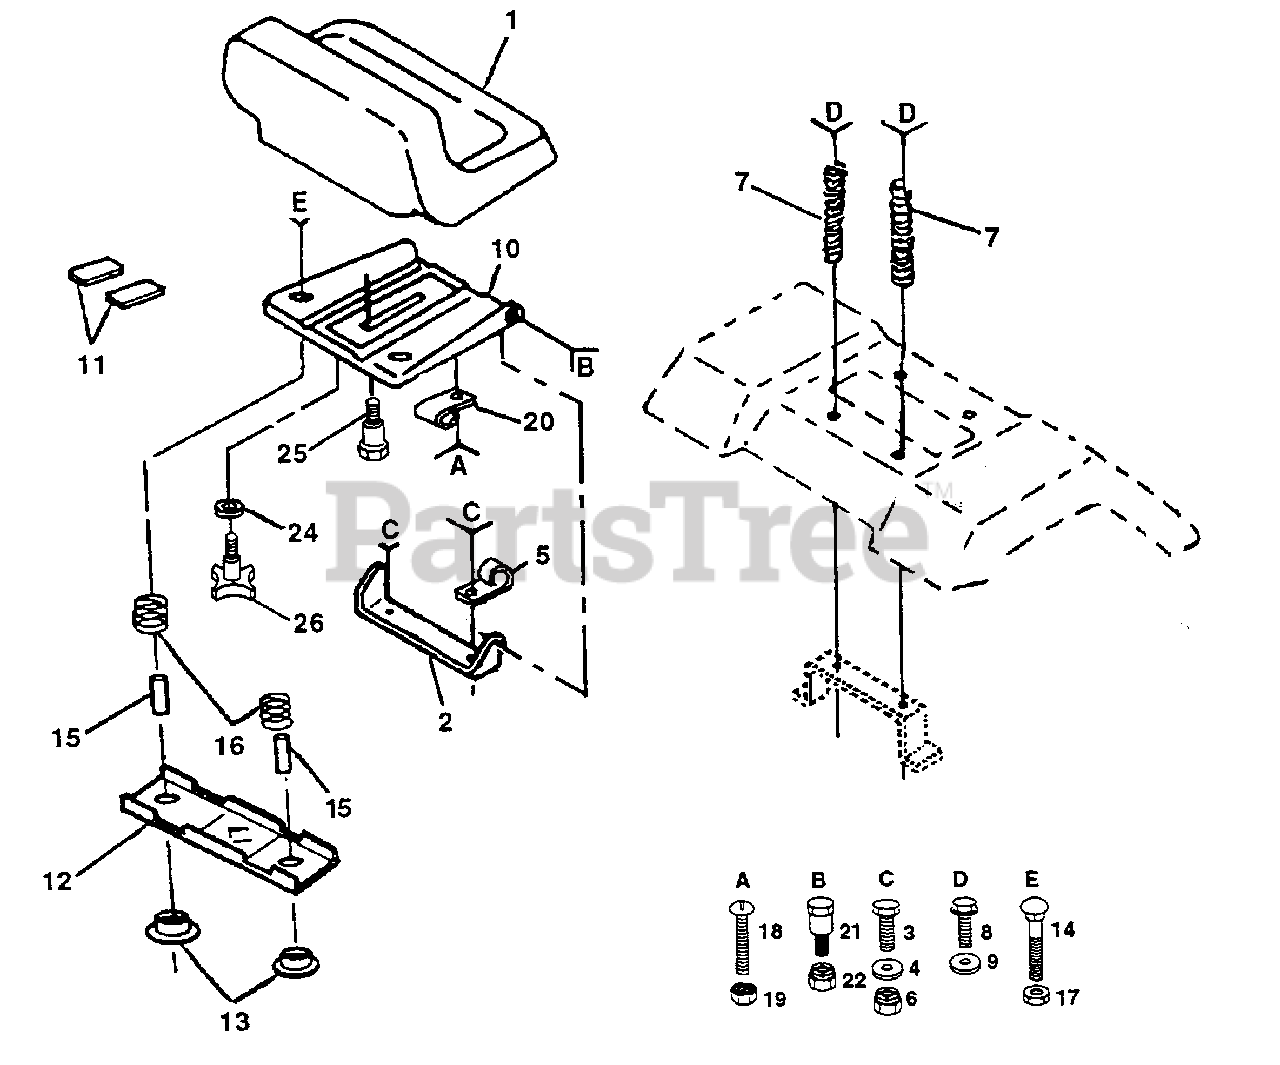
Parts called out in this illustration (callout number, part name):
1	Seat V350 Blk/blk Std
2	Bracket Pivot Seat 8 720
3	Bolt Fin Hex 3/8-16unc X 3/4
4	Washer 13/32 X 1 X 10 Ga
5	Clip Line Fuel 13/32 Mtg Hole
6	Nut Crownlock 3/8-16 Unc
7	Spring Seat Cprsn 2 250 Blk Zi
8	Screw Thdrol 3/8-16 X 1 Ty-tt
9	Washer 13/32 X 1 X 14 Ga
10	Pan Seat
11	Strip Foam Gray Or Black
12	Bracket Mounting Switch
13	Bushing Snap Blk Nyl 50 Id
14	Bolt Rdhd Sht Nk 1/4-20x1-3/8
15	Spacer Split 28x 96 Yel Zinc
16	Spring Cprsn 1 27 Blk Pnt
17	Nut Lock 1/4 Lge Flg Gr 5 Zinc
18	Screw SL TD Pan Hd #10-32 X 1/2
19	Nut Keps #10-32 Unf
20	Clip Insulated 11/32 Mtg Hole
21	Bolt Shoulder 5/16-18 Unc Blkz
22	Nut Crown Lock 5/16-18
24	Washer 17/32 X 1-3/16 X 12 Ga
25	Bolt Shoulder 5/16-18 X 62
26	Knob Seat 1/2-13 Unc Blk
